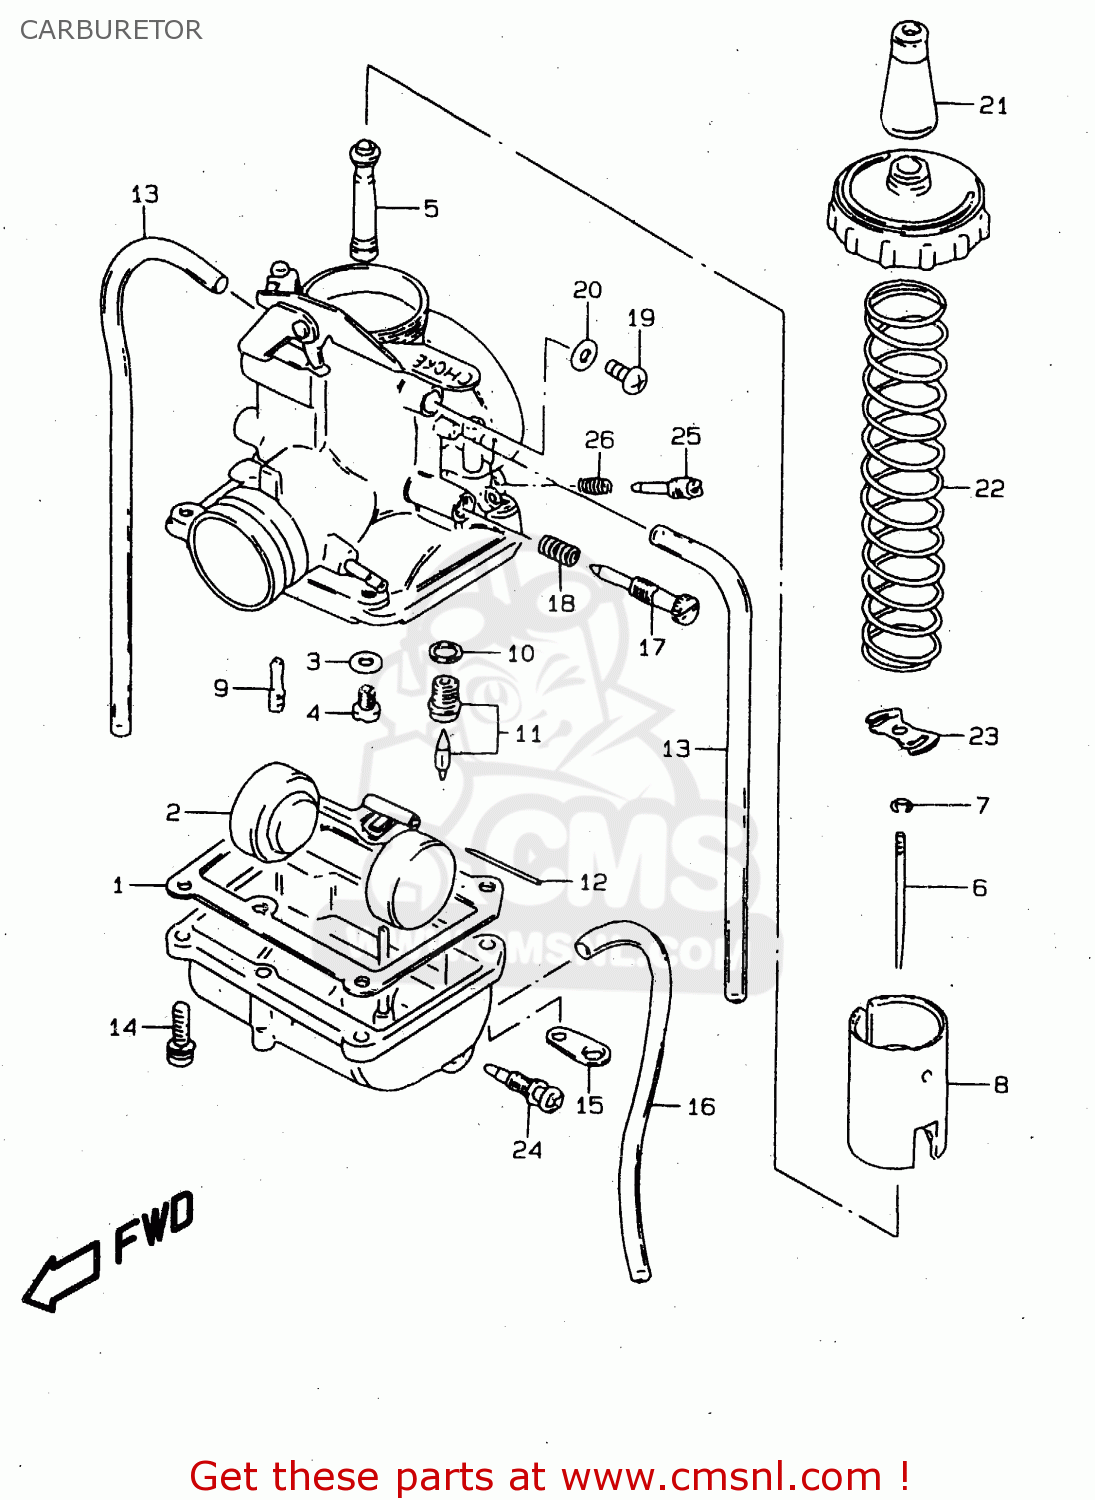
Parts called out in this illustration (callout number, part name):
1	GASKET,FLOAT CHAMBER (NAS)
2	FLOAT
3	WASHER
4	JET,MAIN(87.5)
5	JET,NEEDLE
6	NEEDLE,JET
7	CLIP
8	VALVE,THROTTLE
9	JET,PILOT(25)
10	GASKET,NEEDLE VALVE (NAS)
11	VALVE ASSY,NEEDLE
12	PIN,FLOAT
13	HOSE(3X5X600)
14	SCREW
15	PLATE
16	HOSE(3X5X650)
17	SCREW,THROTTLE STOP
18	SPRING,THROTTLE SCREW
19	SCREW
20	GASKET,DRAIN PLUG (NAS)
21	CAP,CABLE ADJUSTER
22	SPRING,THROTTLE VALVE
23	STOPPER,NEEDLE CLIP
24	PLUG,DRAIN
25	SCREW,PILOT AIR
26	SPRING
